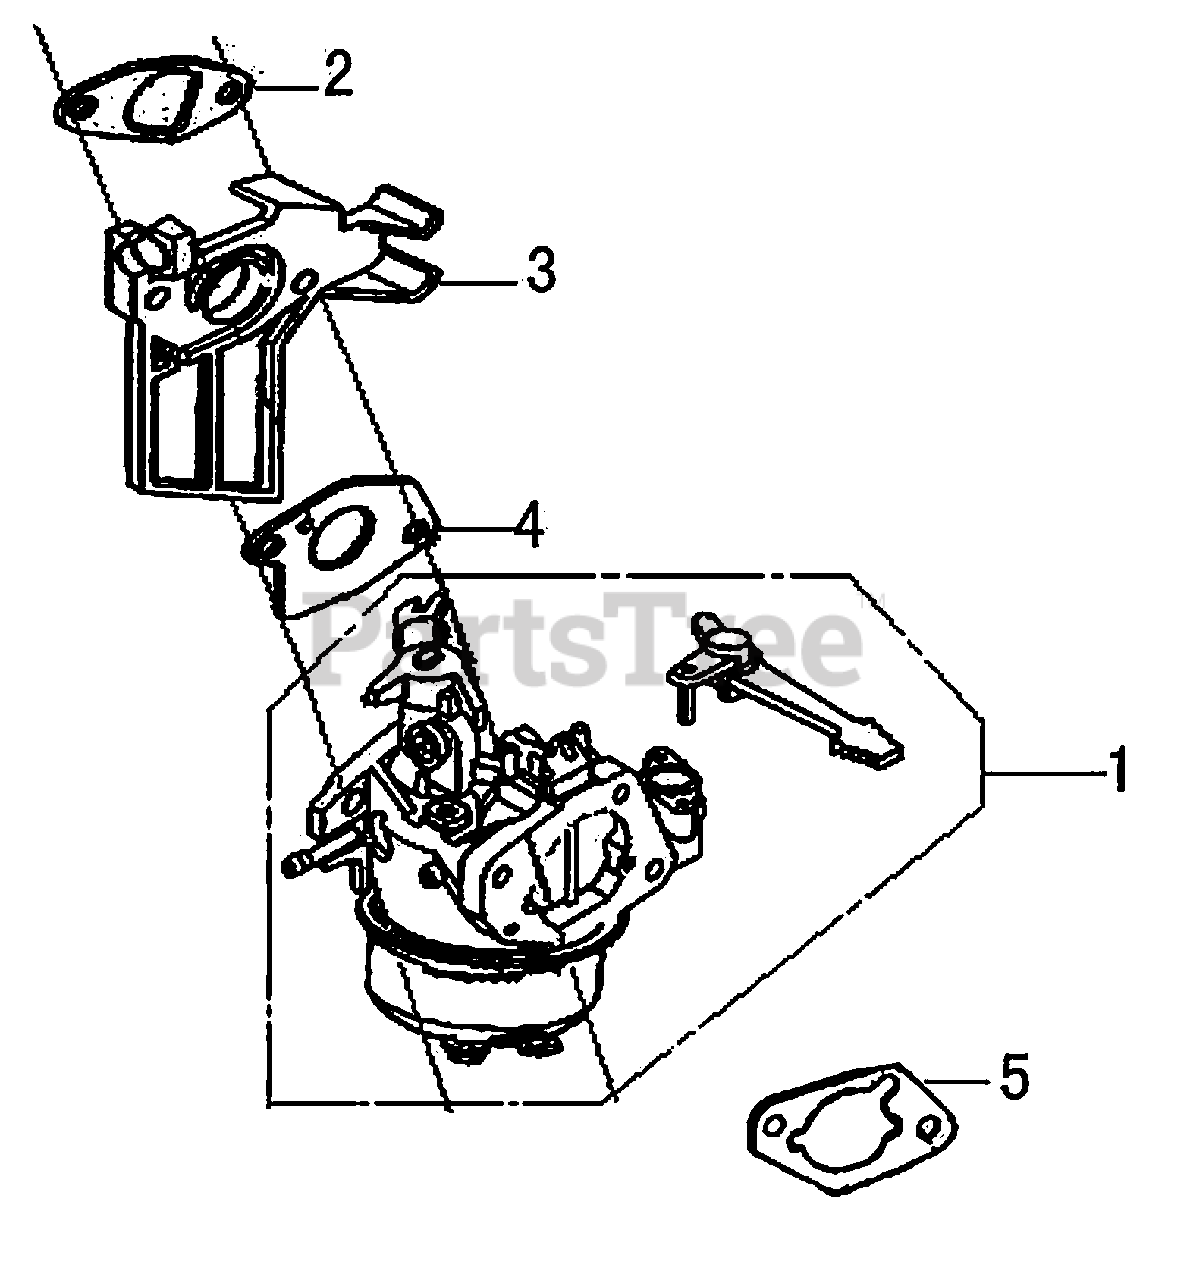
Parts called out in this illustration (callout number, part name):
1	CARBURETOR
2	GASKET, INSULATOR
3	INSULATOR, CARBURETOR
4	GASKET, CARBURETOR
5	GASKET, AIR CLEANER
